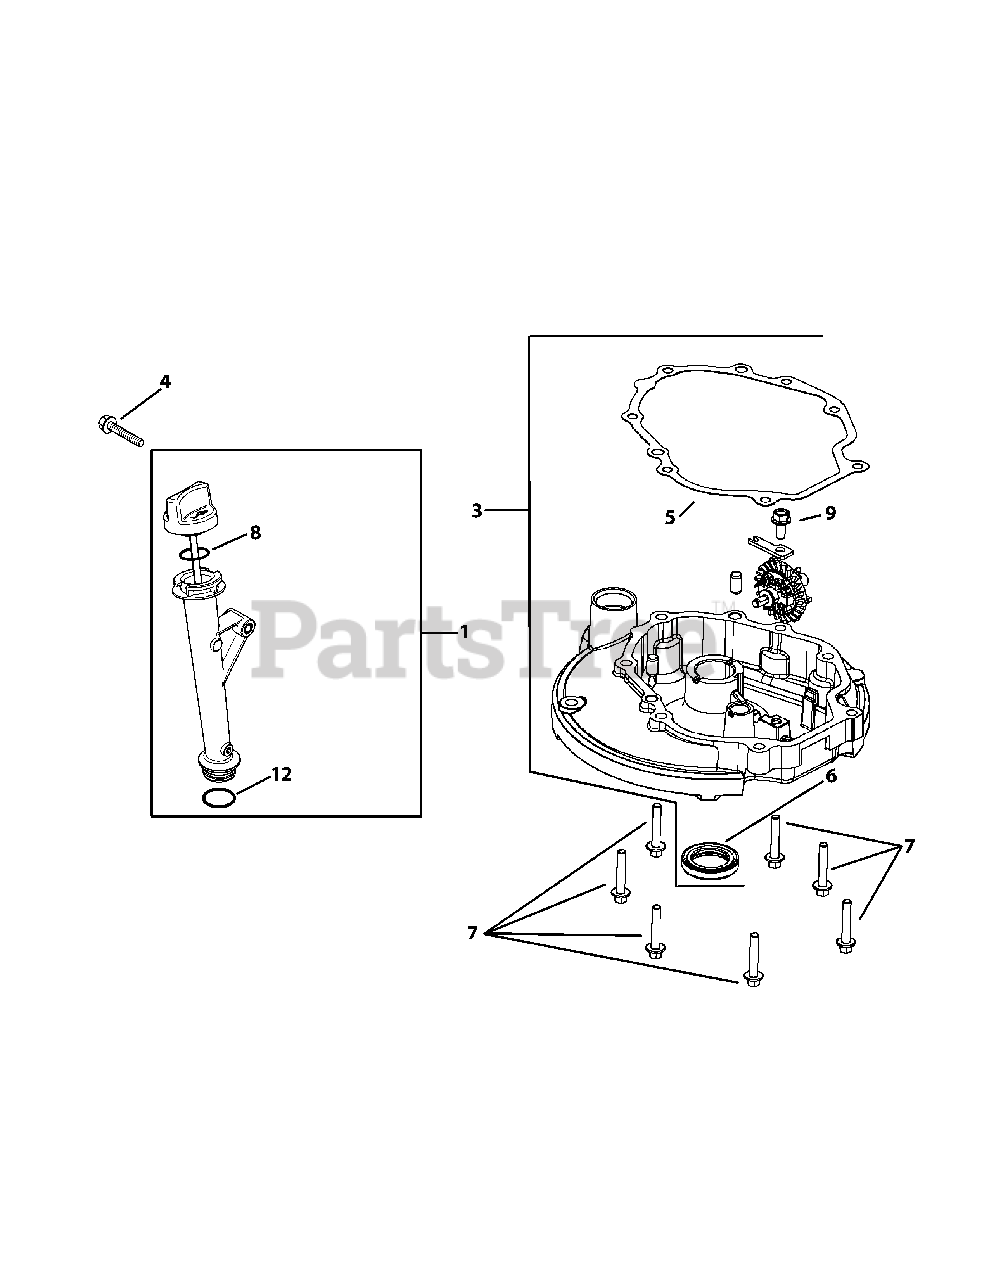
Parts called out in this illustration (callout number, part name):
1	Oil Fill Tube Assembly
2	Oil Fill Tube O-Ring
3	Oil Pan Kit
4	Screw Hex Flange (M6)
5	Gasket Oil Pan
7	Screw Hex Flange (M8)
9	Screw Hex Flange (M6)
12	Oil Fill Tube O-Ring
